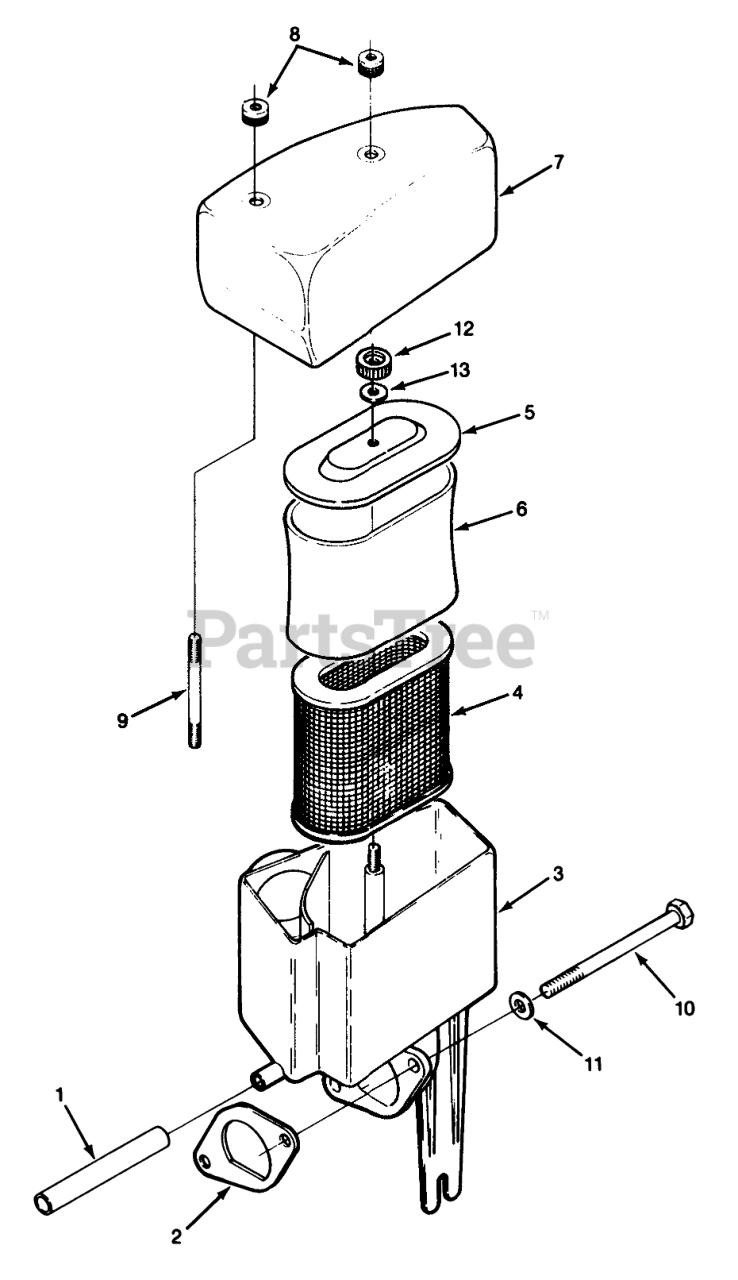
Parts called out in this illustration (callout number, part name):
1	HOSE-BRH 3/8"IDX91MM
2	Gasket
3	Adapter
4	Element
5	COVER-ELEMENT
6	WRAPPER-ELEMENT
7	Air Cleaner Cover
8	KNOB M6
10	HHCS-M8 X 100MM
11	Nut-M8
13	GROMMET
